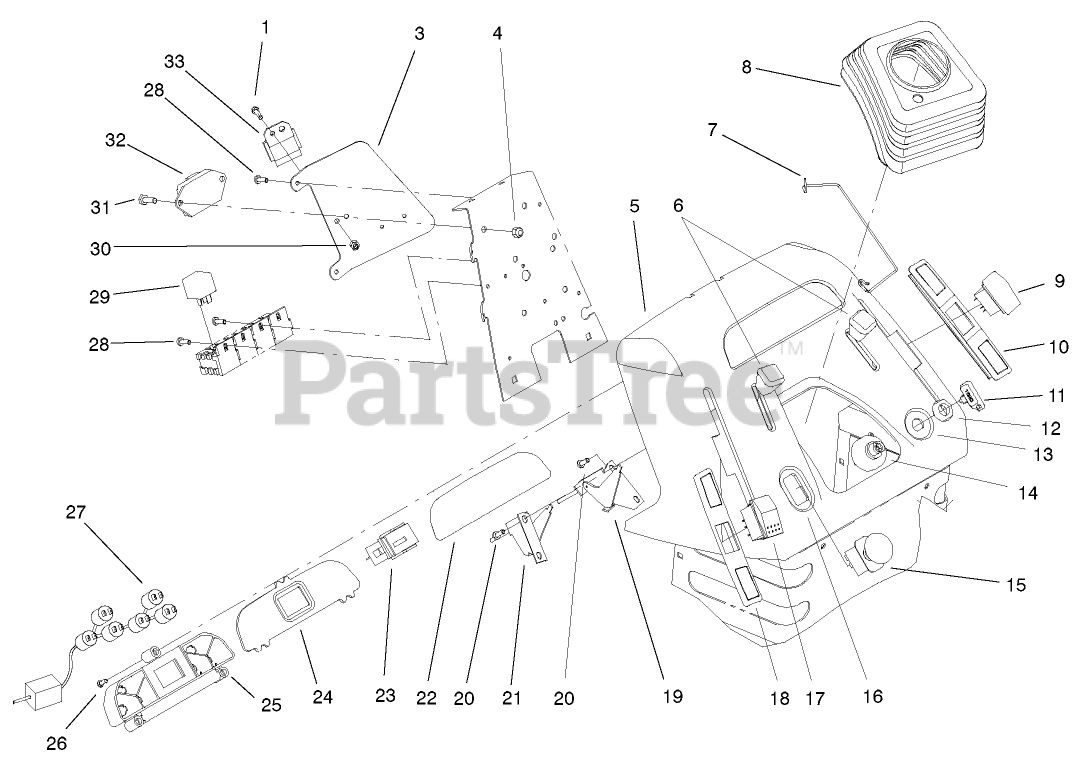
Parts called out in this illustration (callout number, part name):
3	PANEL-SUPPORT, AUX
4	NUT-LOCK, NI
7	CLIP-BOOT
8	BOOT-STEERING
9	SWITCH-CRUISE
10	COVER-SLOT, RH
11	KEY-IGNITION
13	DECAL-DASH
13	DECAL-THROTTLE, IGNITION
14	SWITCH-IGNITION
15	SWITCH-PTO,ON-ON-NONE
16	DECAL-DASH, PTO/CHOKE
16	DECAL-PTO / CHOKE
17	SWITCH
18	COVER-LIFT
19	CONTROL-THROTTLE (TWIN)
21	CONTROL-CHOKE (TWIN)
22	DECAL - DASH LENS
23	HOURMETER
24	LENS-DASH
25	HOUSING-LIGHT
26	SCREW
27	HARNESS-6 LAMP
28	SCREW-PPHTF
29	RELAY
30	NUT-LOCK, NI
31	SCREW-HH
32	MODULE-CLUTCH
33	MODULE-LOW VOLTAGE
